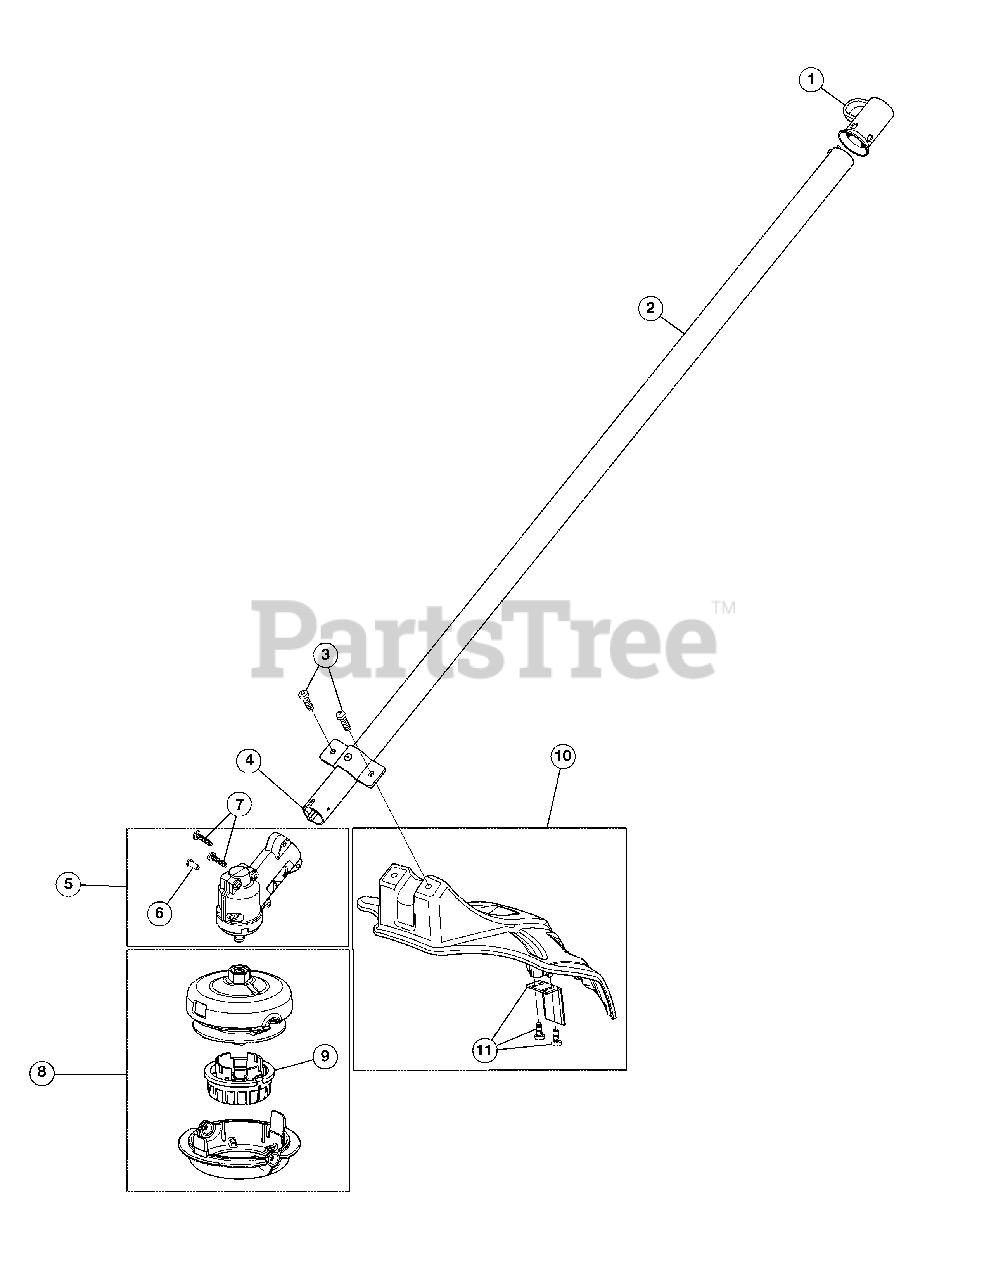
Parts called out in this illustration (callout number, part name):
1	Hanger
2	Lower Drive Shaft Housing Assembly
3	Shield Mounting Screws
4	Lower Flexible Drive Shaft
5	Gear Box Assembly (Incl. 6 & 7)
6	Anti-Rotation Screw
7	Gearbox Mounting Hardware
8	Cutting Head Assembly (Incl. 9)
9	Bump Knob
10	Shield Assembly (Incl. 11)
11	Blade Assembly
